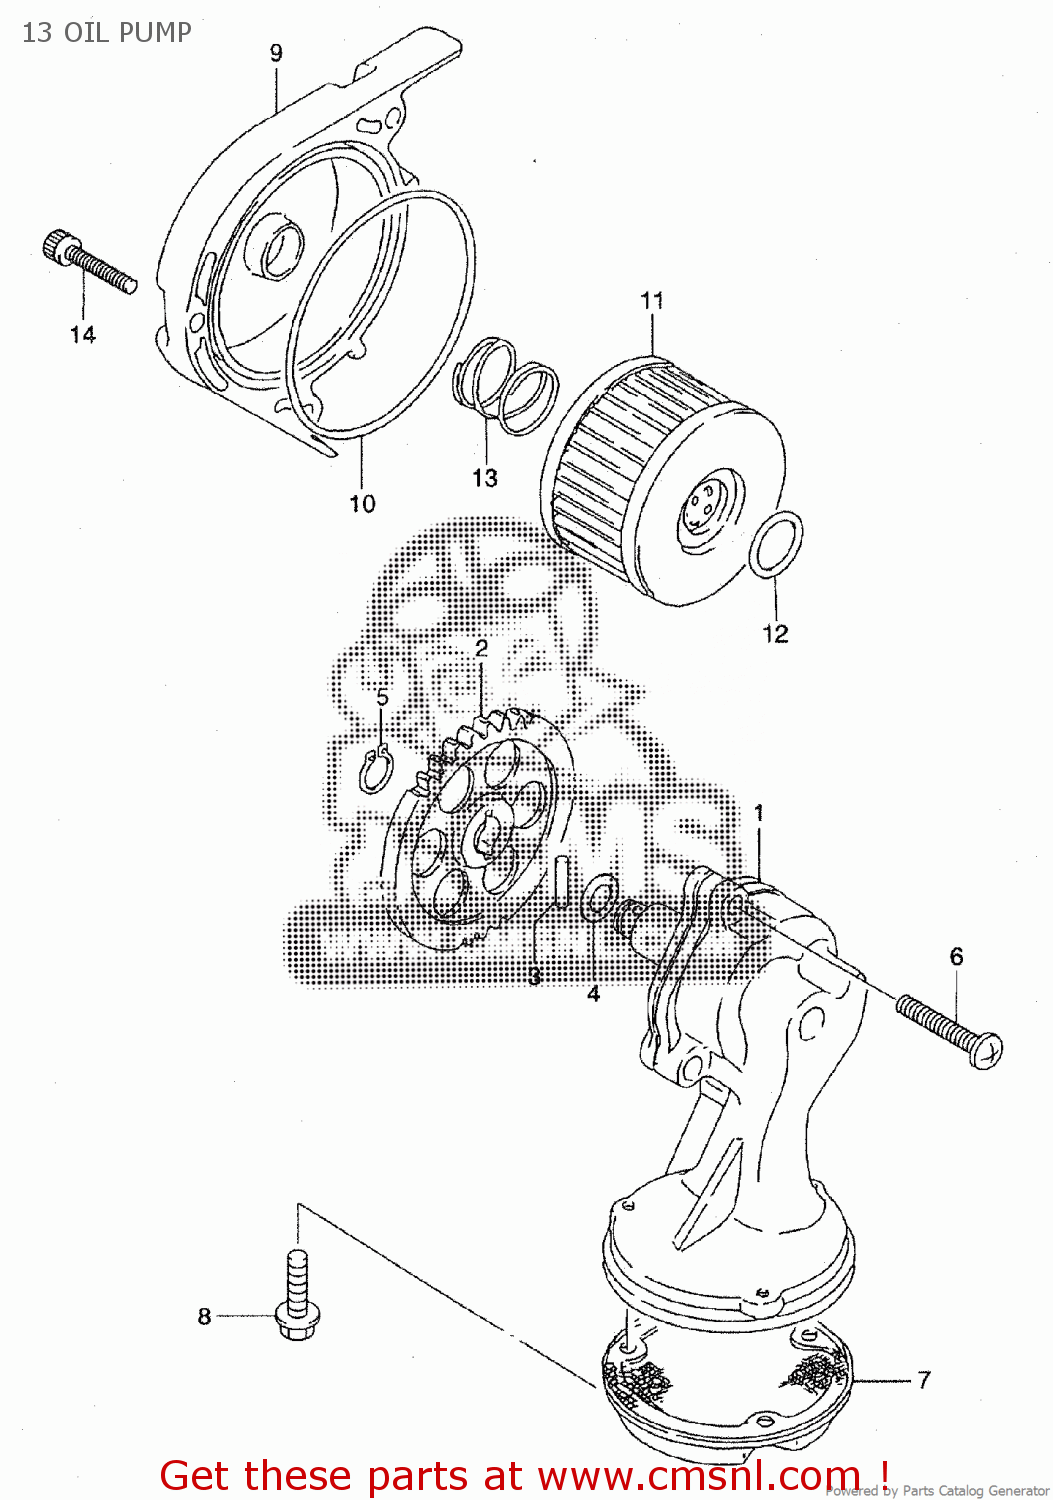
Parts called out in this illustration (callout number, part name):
1	PUMP ASSY,ENGINE OIL
2	GEAR,ENG OIL PUMP DRIVEN
3	PIN(4X15.8)
4	SHIM(10X18X0.5)
5	CIRCLIP,10MM
6	SCREW
7	STRAINER,ENGINE OIL
8	BOLT
9	CAP,OIL FILTER
10	O RING(D:2.4,ID:73)
11	FILTER ASSY,ENGINE OIL
12	O RING(D:2.4,ID:15.8)
13	SPRING
14	BOLT
